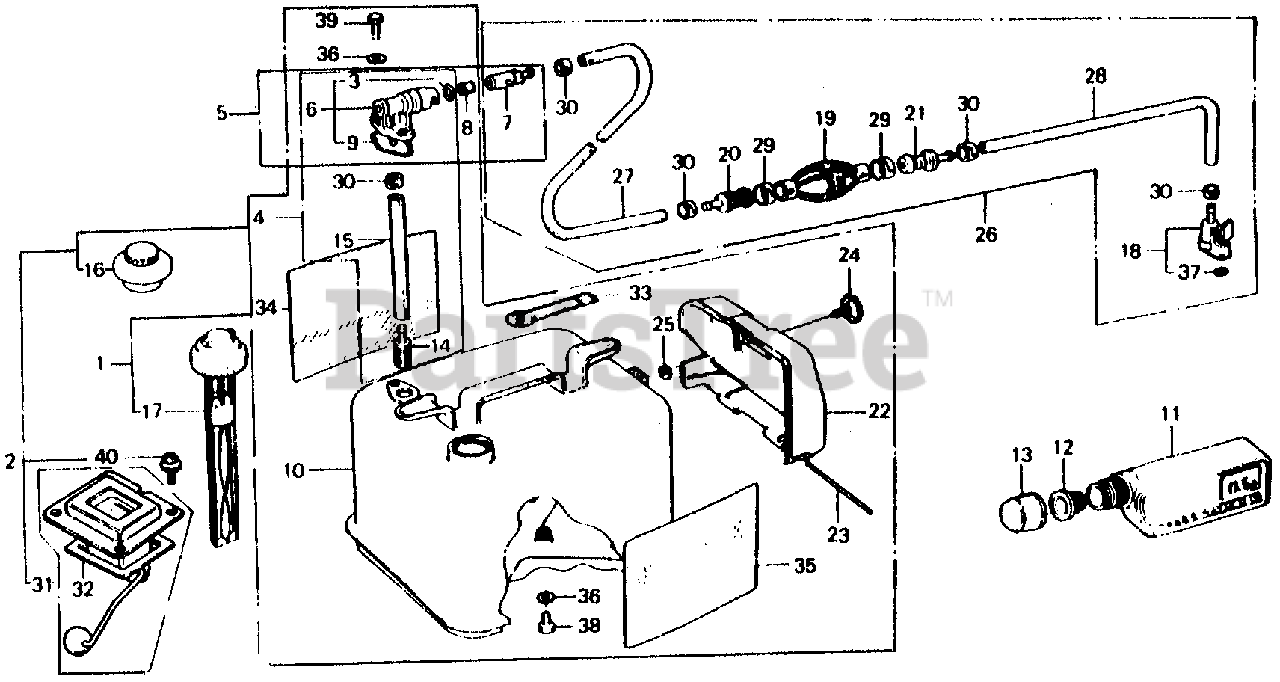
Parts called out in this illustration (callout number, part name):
2	TANK KIT, FUEL *R8* (BRIGHT RED)
2	TANK KIT, FUEL
4	JOINT A, FUEL
5	JOINT, FUEL CONSENT (NOT AVAILABLE)
6	JOINT A, FUEL CONSENT
7	JOINT B, FUEL CONSENT
8	ABSORBER, FUEL
9	RING, PETCOCK SEAL
10	TANK, FUEL *R8* (BRIGHT RED) (NOT AVAILABLE)
11	TANK, OIL (NOT AVAILABLE)
12	CAP, SUB-TANK (INNER) (NOT AVAILABLE)
13	CAP, SUB-TANK (NOT AVAILABLE)
14	FILTER, FUEL
15	TUBE (INNER)
17	CAP, FUEL FILLER (NOT AVAILABLE)
18	CONNECTOR, FUEL *NH1* (BLACK)
19	BULB, PRIMER
20	VALVE, IN.
21	VALVE, OUTLET
22	BOX, TOOL (NOT AVAILABLE)
23	BAR (3X150) (NOT AVAILABLE)
24	LATCH, TOOL BOX (NOT AVAILABLE)
25	STOPPER, LATCH (NOT AVAILABLE)
26	TUBE, FUEL *B9* (ATLANTIS BLUE) (N/A: SEE COMPONENTS)
27	TUBE, FUEL LONG (NOT AVAILABLE)
28	TUBE, FUEL SHORT
29	BAND, TUBE CLIP (20MM)
30	BAND, TUBE CLIP (11MM)
33	MARK, TANK CAUTION (ENGLISH/FRENCH)
34	MARK B, TANK (ENGLISH)
35	MARK, TANK (FRENCH)
36	GASKET, FIBER (6MM)
37	O-RING (5.5MM)
38	BOLT, HEX. (6X12)
39	BOLT, HEX. (6X16)
